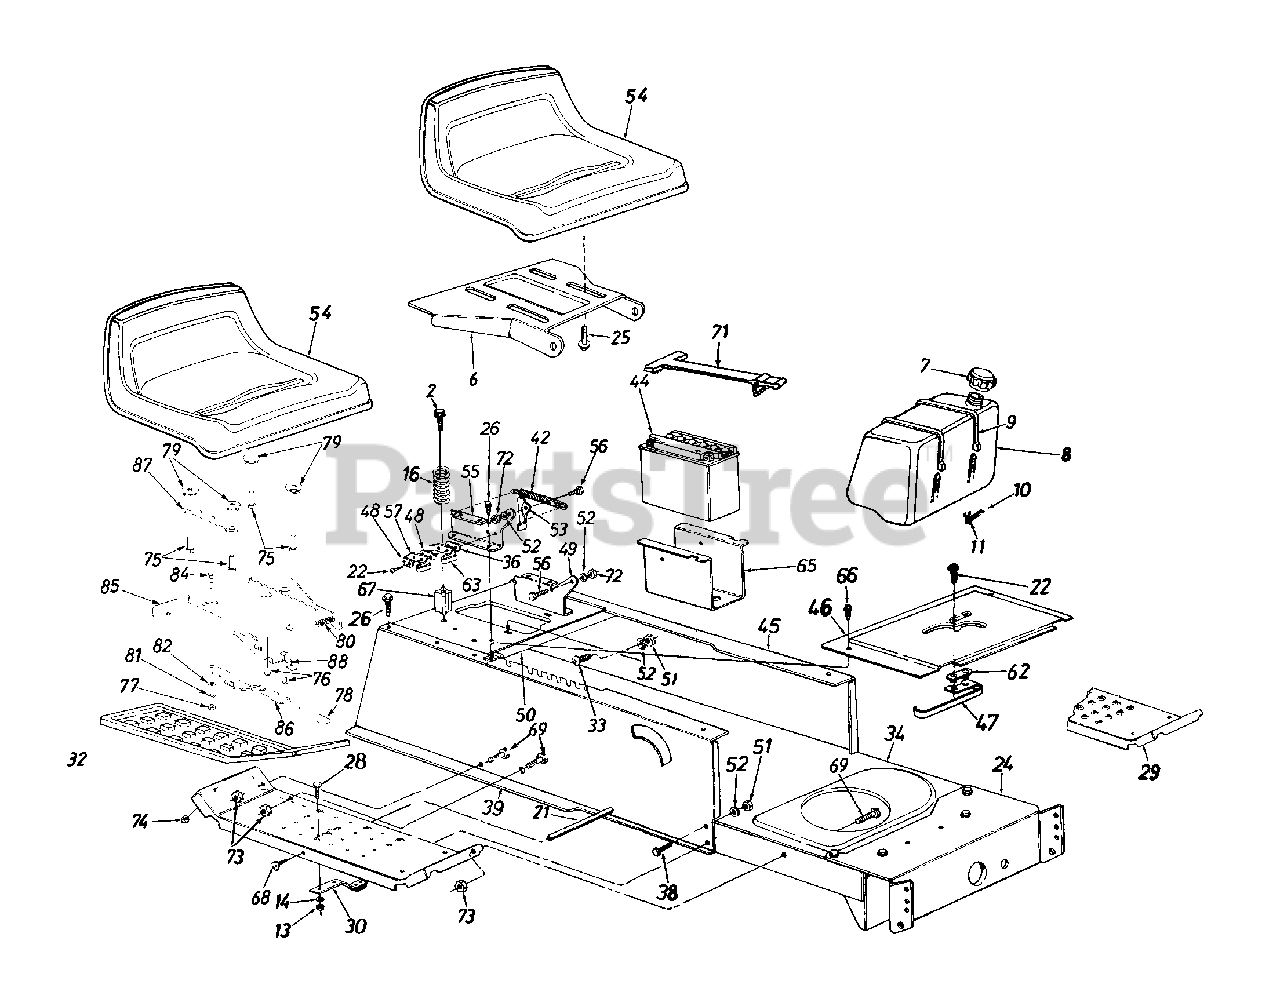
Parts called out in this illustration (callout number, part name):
2	Hex Tap Scr. 5/16-18 x 3.25"
7	Fuel Cap
8	Fuel Tank
9	Tie Strap
10	Fuel Line
11	Hose Clamp
13	Hex Nut 1/4-20 Thd.
14	Lock Washer 1/4" I.D.
16	Compression Spring
21	Running Board Rod
22	Hex AB-Tap Scr. #8 x .50" Lg.
25	Hex Tap Scr. 3/8-16 x .62" Lg.
26	Hex Wash. Hd. AB-Tap Scr .5/16 x .75"
28	Carriage Bolt 1/4-20 x .62"
32	Rubber Foot Pad- LH
36	Insulator Boss Plate
38	Hex Bolt 5/16-18 x .75" Lg.
44	12-V Battery
48	Insulator Plate
49	Seat Pivot Brkt. Support- LH
52	Lock Washer 5/16" I.D.
53	Seat Lift Brkt.
54	Seat 8-7/8" High
56	Shld. Bolt .437" Dia. x .268"
57	Spring Switch (Seat- Outer)
63	Safety Switch (Seat- Inner)
66	Truss Mach. B-Tap Scr.#10 x .5" Lg.
67	Spring Spacer
68	Truss Mach. Scr. 5/16-18 x .75"
69	Hex Bolt 5/16-18 x .75" Lg.
71	Battery Retainer Strap
72	Hex Nut 5/16-18 Thd.
73	Hex Sems Nut 5/16-18 Thd.
74	Hex Sems Nut 1/4-20 Thd.
75	Shoulder Screw 3/8-16 x .5
76	Hex Wash. B-Tap Scr. #10-16 x .38"
77	Hex Flanged Lock Nut 1/4-20 Thd.
78	Seat Adjustable Grip
79	Spacer
80	Compression Spring 1.5" Lg.
81	Spring Washer .265" I.D. x .56" O.D.
82	Flat Washer .344" I.D. x .62" O.D.
84	Shld. Bolt .34" x 1/4 -20 Thd.
87	Seat Selector
88	Seat Stop
